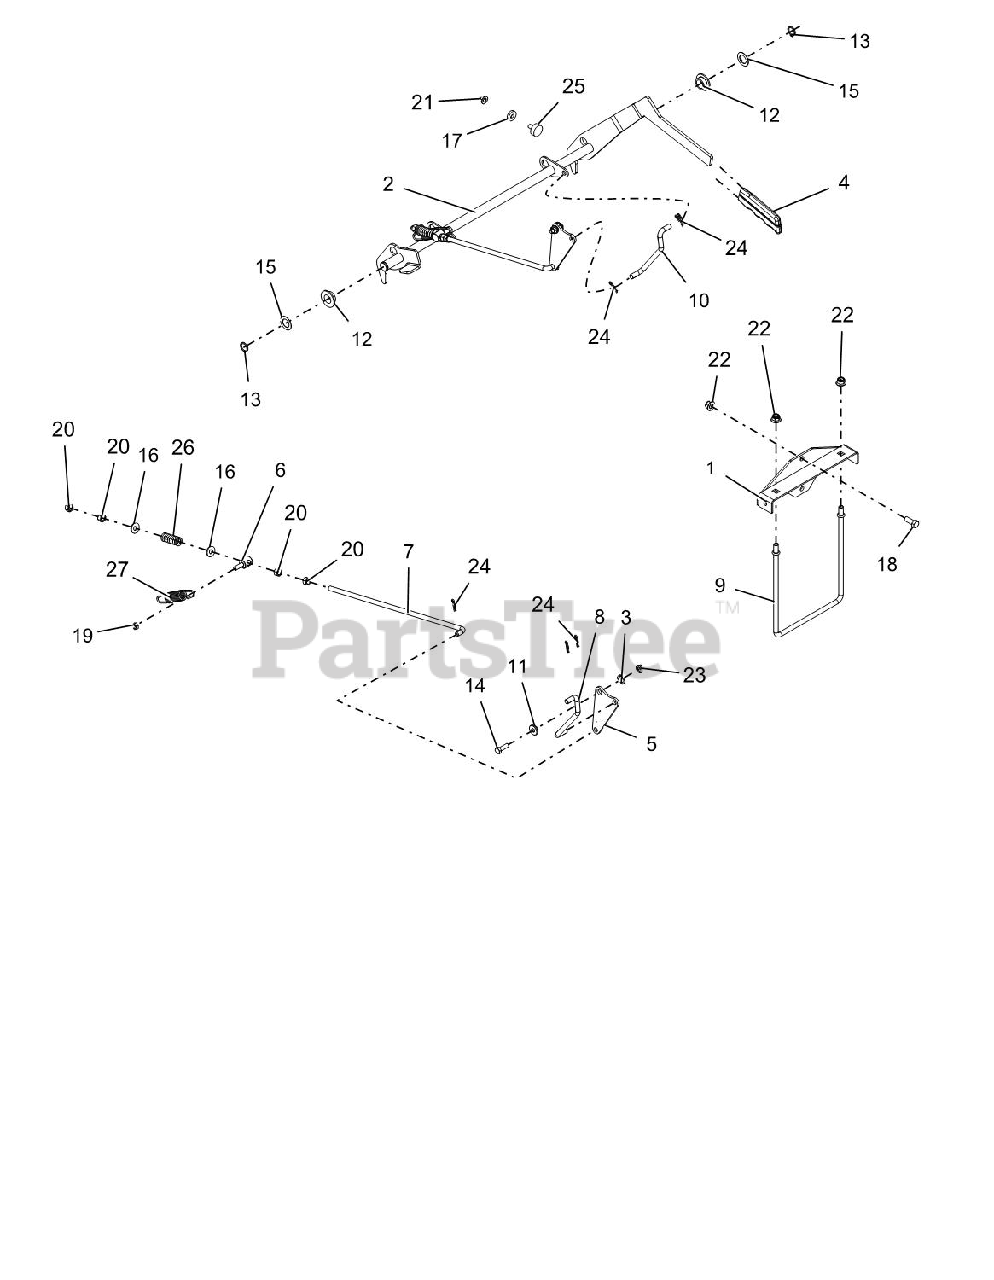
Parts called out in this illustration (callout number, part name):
1	WMT, SPRING ANCHOR BRKT-BLACK
2	WLDMT, PT200/400 PARK BRAKE - GAS
3	WAVE WASHER .531X.781X.125 FH
4	GRIP, PARKING BRAKE (YELLOW)
5	PLATE, BRAKE PIVOT-BLACK
6	TRUNNION, .31-18
7	ROD, BRAKE ADJ.
8	LINKAGE, RH BRAKE ACTUATING
9	ROD, BRAKE MTG
10	LINKAGE, LH BRAKE ACTUATING
11	BSHG, FLG .32X.500.344X.880
12	BSHG, FLANGE .762 X 1.48 X .44 NYLON
13	RG-RTNG-EXT .750x.078
14	BLT-HEX .31-18X1.00 GR5 YWZC
15	WSHR-HDND-THRST
16	WSHR-FL-STL.38X.875X.083 YWZC
17	WSHR-FL-STL .328X.87X.179 YWZC
18	BLT-HEX .38-16X1.00 GR5 YWZC
19	NUT-LK-CTR-JAM .31-18 YWZC
20	NUT-HEX .38-16 YWZC
21	@NUT-SPNLK-FLG .312-18 YWZC
22	NUT-LK-NYL-FLG .38-16 YWZC
23	NUT, LK-TOP-FLG .312-18 YWZC
24	PIN-HAIR, ENDRIES #25 YWZC
25	BUMPER, RUBBER
26	SPRG, COMPRESSION
27	SPRG, TENSION .105 X .850 X 4.880
